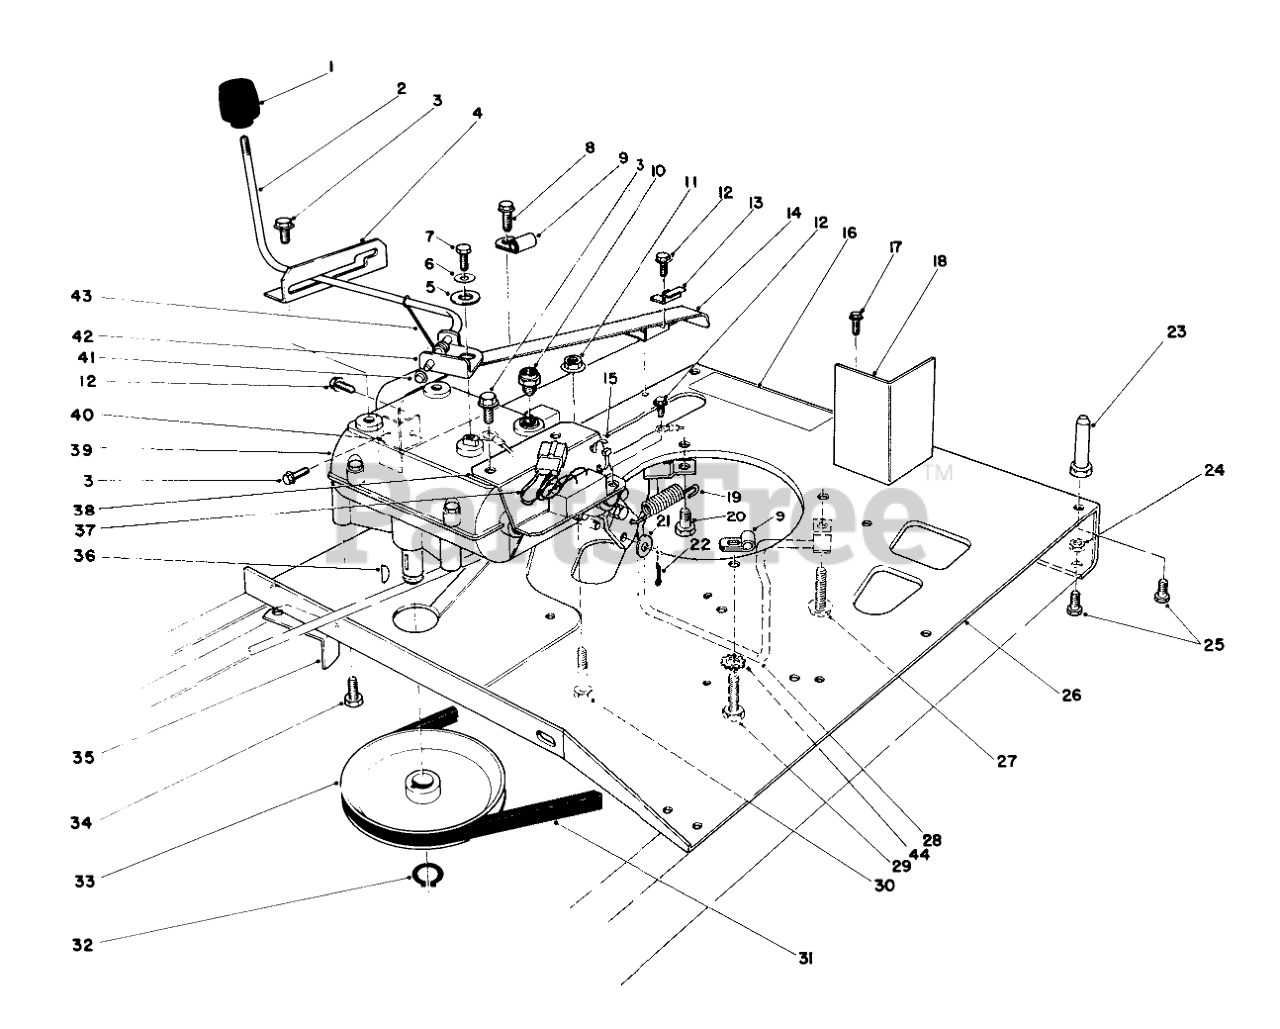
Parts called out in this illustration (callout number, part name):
2	SHIFT LEVER
3	SCREW-HWHTF
4	SHIFT LEVER GATE
5	WASHER-FLAT
6	WASHER-BELLEVILLE
7	SCREW-HH
8	SCREW-HHFTF
9	CLIP-FUEL LINE
10	NEUTRAL SWITCH
11	NUT-HF
12	SCREW-HWH
13	Clamp-Cable
14	Chain Guard
15	TIE-CABLE
16	DECAL
17	SCREW-HH
18	Baffle-Carb
19	SPRING-RETURN, BRAKE
20	Screw-HH
21	WASHER-FLAT
22	PIN-COTTER
23	PIN-MOUNTING, LOWER
24	NUT-LOCK, NI
25	SCREW-HH
26	Plate-Engine
27	SCREW-HWHTF
28	BELT GUIDE WA B
29	SCREW-HH
30	SCREW-HH
31	V-BELT
32	RING-SNAP, EXTERNAL
33	PULLEY
34	Screw-Hex. Hd.
35	TRANS BELT RET B
36	KEY-WOODRUFF
37	INTERLOCK MODULE
38	Mount Module
39	TRANSMISSION
40	CHAIN GUARD BRKT B
41	RETAINER-PUSH ON
42	SHIFT LEVER CLAMP
43	Spring-Shift Rod
44	WASHER-LOCK
